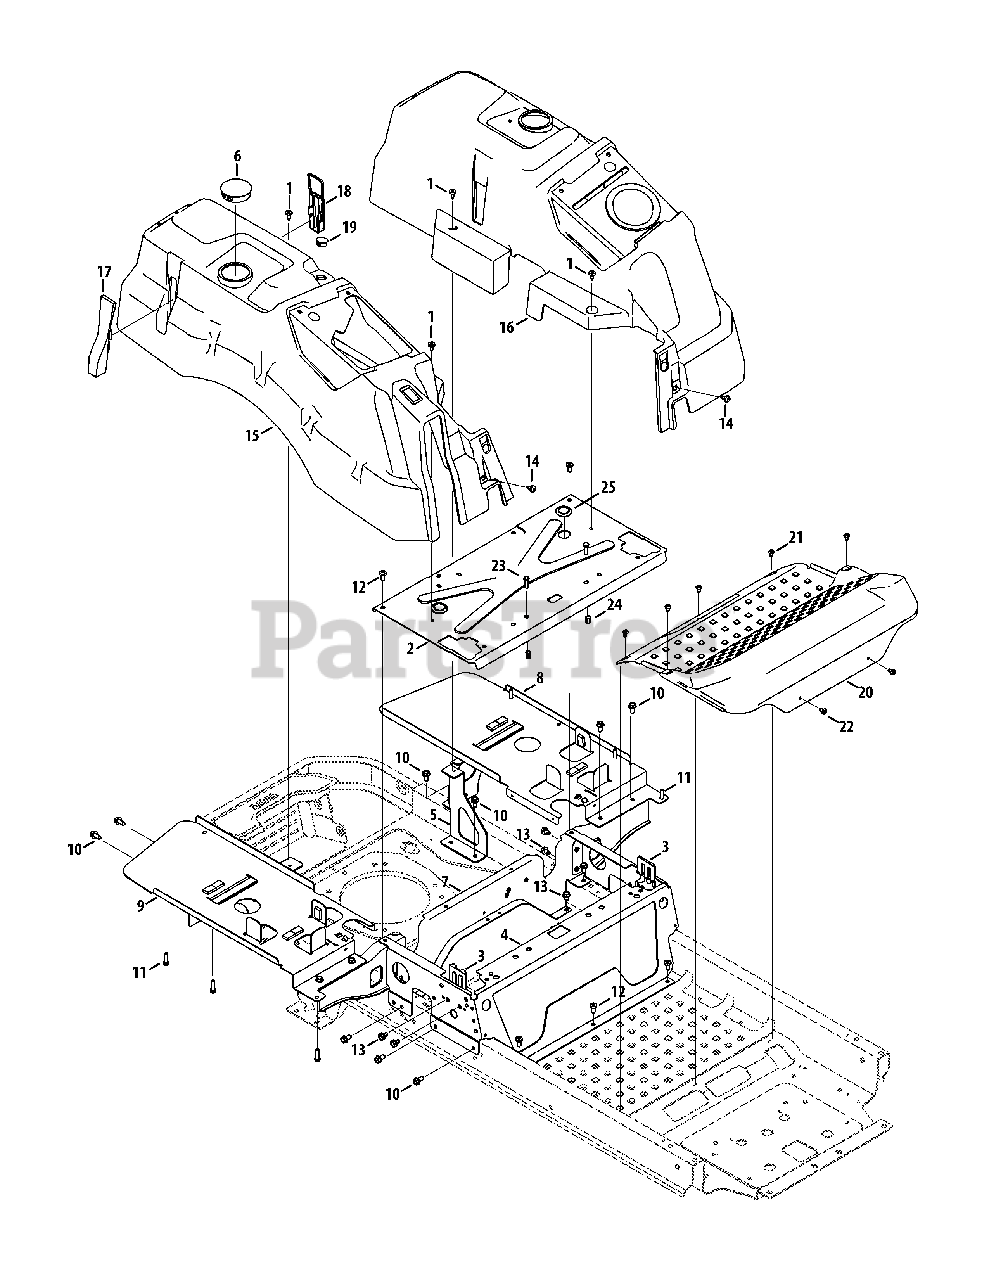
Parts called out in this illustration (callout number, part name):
1	Shoulder Screw, .368 x .115, M6-1
2	Seatbox Plate
3	Lapbar Brace Bracket
4	Seat Frame
5	Rear Support Bracket, LH
5	Rear Support Bracket, RH
6	Plug, 2.50 Dia.
7	Rear Seatbox Brace
8	Tank Support Plate, LH
9	Tank Support Plate, RH
10	Hex Washer Screw, 5/16-18 x .750
11	Hex Washer Screw, 5/16-14 x 1.00
12	Self Tapping Screw, 5/16-18 x .750
13	Hex Washer Screw, 5/16-18 x .50
14	Shoulder Screw, 1/4-20
15	RH Console
16	LH Console
17	Outer Pod Plug
18	Inner Pod Plug
19	Plug, .875 Dia.
20	Floor Board
21	Screw, 1/4-20 x .50, Black
22	Screw, 5/16-18, .750
23	Hex Cap Screw, 5/16-18 x 1.00
24	Nut, 5/16-18
25	Button Plug
